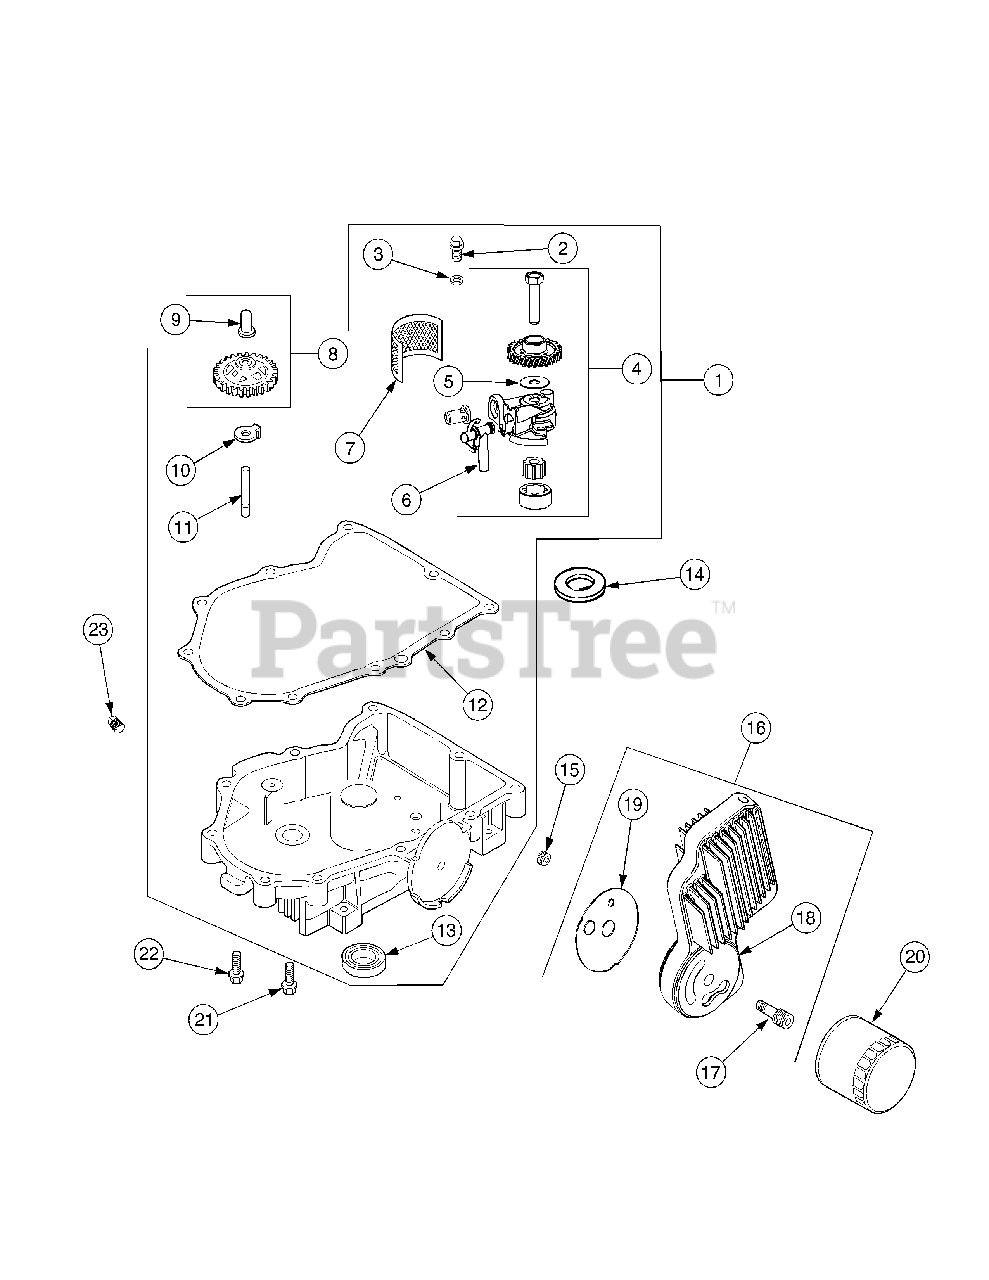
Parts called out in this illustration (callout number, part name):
1	Kit, Oil Pan, Includes 2-13
2	Screw, Hx Flange, M6 -1.0 x 25
3	Washer, 6mm
4	Oil Pump Ass’y., Includes 5, 6
6	Tube, Oil Pick-up
8	Kit, Governor Gear
9	Pin, Governor Regulating
11	Shaft, Governor Gear
12	Gasket, Oil Pan
13	Seal, Oil
15	Plug, 3/8 Hex Ctsk
16	Kit, Oil Cooler
17	Nipple, Oil Filter
19	Gasket, Oil Filter Adapter
20	Filter, Oil
21	Screw, Hx Flange, M8-1.25 x 45
22	Screw, Hx Flange, M8-1.25 x 45
23	Plug, Pipe, 3/8
